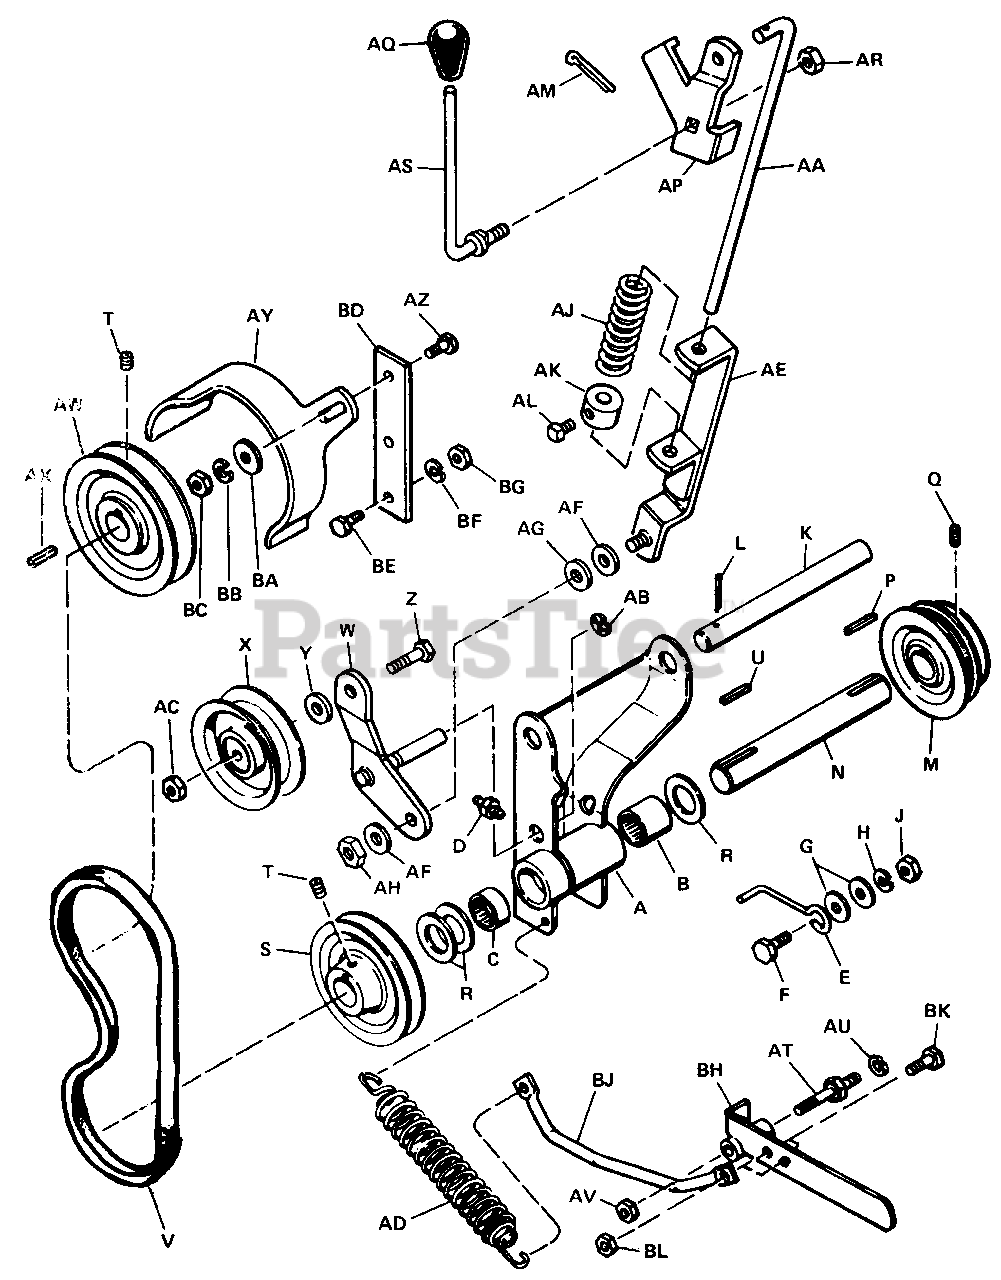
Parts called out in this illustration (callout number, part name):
A	Bracket, P.T O. Assy.
B	Bearing, Roller
C	Bearing, Roller
D	Grease Fitting
F	Hex Capscrew, 5/16"-18 x 1-1/4"
G	Plain Washer, 5/16"
H	Lock Washer, 5/16"
J	Full Hex Nut, 5/16"-18 N.C.
K	Rod Pivot, 5/8" Dia. x 6-13/16"
L	Cotter Pin
N	Shaft, P.T.O.
Q	Cup Pt. Skt. Hd. Screw Set, 5/16" 18 N.C. x 1/4"
S	Pulley, P.T.O.
T	Cup Pt. Skt. Hd. Screw Set, 5/16" 18 N.C. x 5/16"
V	BELT, B-Sect, 28.94"
W	Idler Lever Assy.
X	Idler Pulley
Y	Plain Washer, 5/16"
Z	Hex Cap Screw, 3/8"-16 N.C. x 1-1/4"
AA	Clutch Rod, P.T.O.
AB	Retaining Ring
AC	Center Jam, 3/8" 16 N.C.
AD	Spring, Tension
AE	Rod Guide Assy.
AF	Plain Washer, 5/16"
AG	Washer, Special
AH	Elastic Stop Nut, 5/16"-18 N.C.
AL	Cup Pt. Sq. Hd. Screw Set, 1/4"-20 N.C. x 3/8"
AM	Cotter Pin, 3/32" x 1/2"
AN	Full Lock Hex Nut, 3/8"-16 N.C.
AP	Clutch Lever Assy. P.T.O.
AQ	Knob, P.T.O.
AR	Full Lock Hex Nut, 3/8"-16 N.C.
AS	Clutch Handle, P.T.O.
AU	Lock Washer, 7/16"
AV	Full Lock Hex. Nut, 7/16"
AY	Guard Belt
AZ	Hex Cap Screw, 3/8"-16 N.C. x 1"
BA	Plain Washer, 3/8"
BB	Lock Washer, 3/8"
BC	Full Hex Nut, 3/8"-16 N.C.
BD	Guard Belt Support, 3/16" x 1-1/4" x 5-7/16"
BE	Hex Cap Screw, 5/16"-18 N.C
BF	Lock Washer, 5/16"
BG	Full Hex Nut, 5/16"-18 N.C.
BH	Handle Assy.
BJ	Spring Tension Rod
BK	Hex Cap Screw, 5/16"-18 N.C. x 3/4"
BL	Full Lock Hex Nut, 5/16"-18 N.C.
